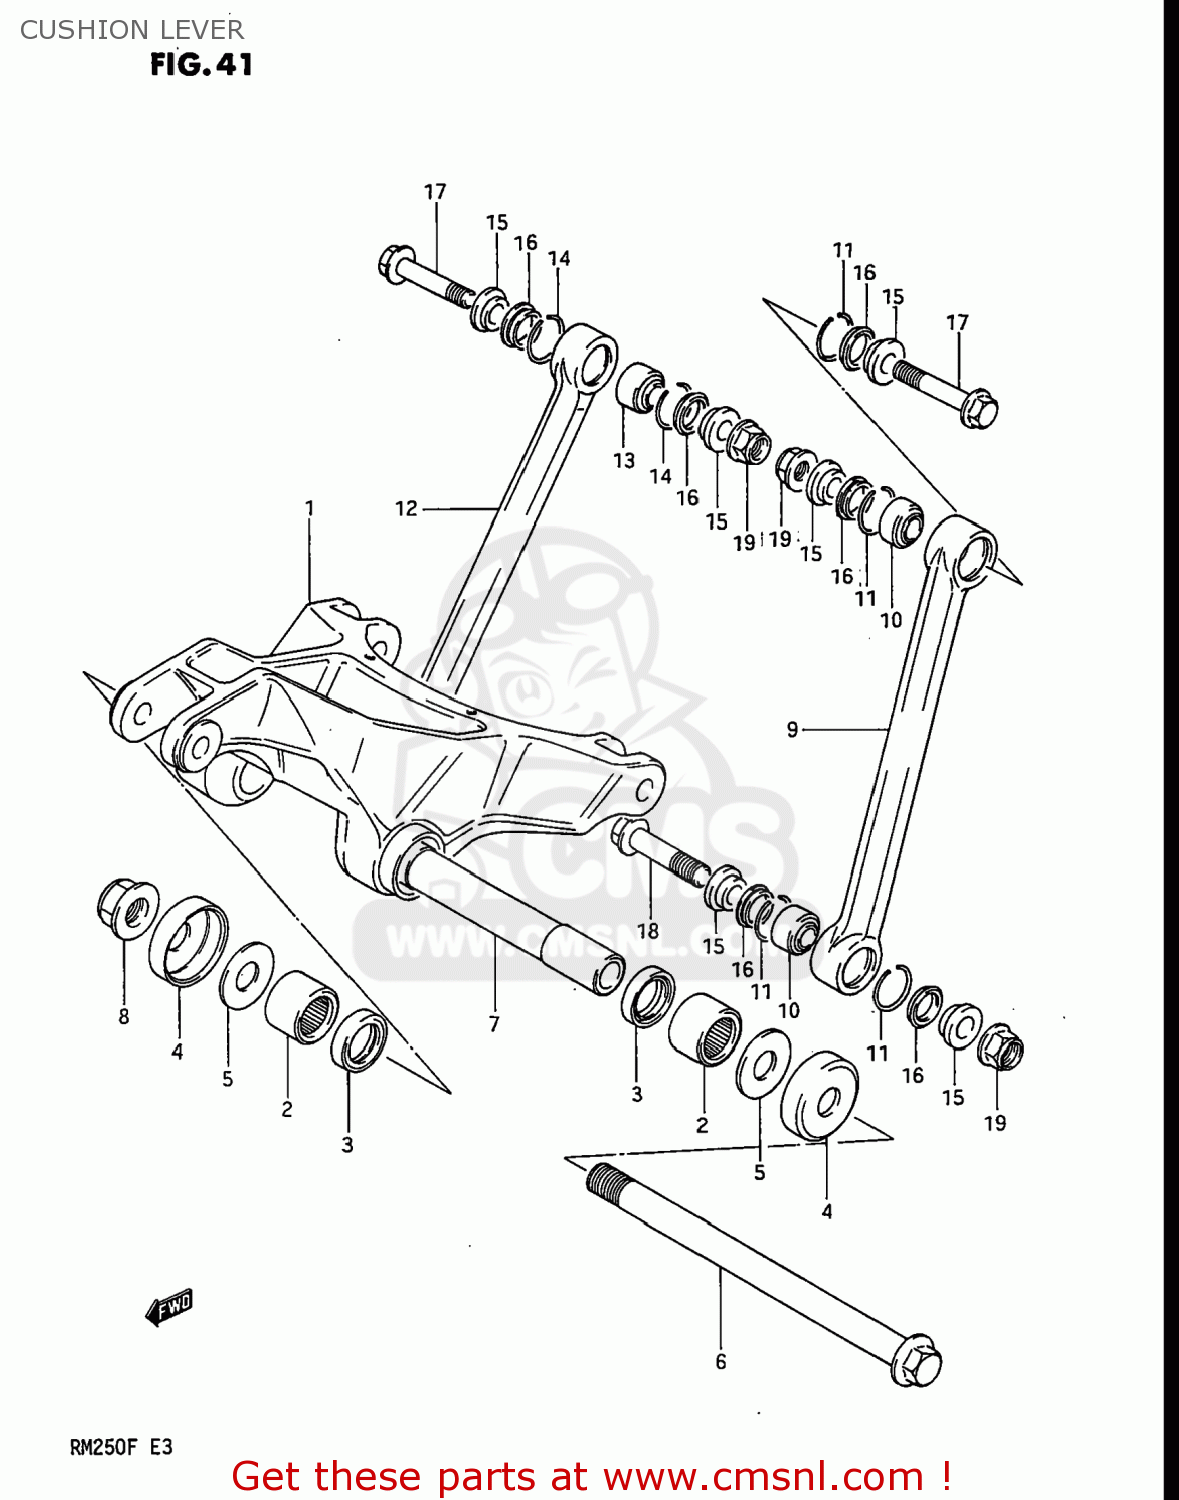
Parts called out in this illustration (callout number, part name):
1	LEVER SET,REAR CUSHION
2	BEARING(20X27X25)
3	SEAL,CUSHION LEVER DUST
4	CVR,RR SWGARM DUST SEAL(OD:40)
5	WASHER
6	SHAFT,REAR CUSHION LEVER
7	SPACER,REAR CUSHION LEVER
8	NUT
9	LEVER SET,REAR CUSHION
10	BEARING(10X21X13)
11	RING,BEARING STOPPER
12	LEVER SET,REAR CUSHION
13	BEARING(10X21X13)
14	RING,BEARING STOPPER
15	SPACER,REAR CUSHION ROD
16	DUST SEAL,RR CUSHION ROD
17	BOLT,RR CUSHION ROD UPR
18	BOLT,RR CUSHION ROD LWR
19	NUT
